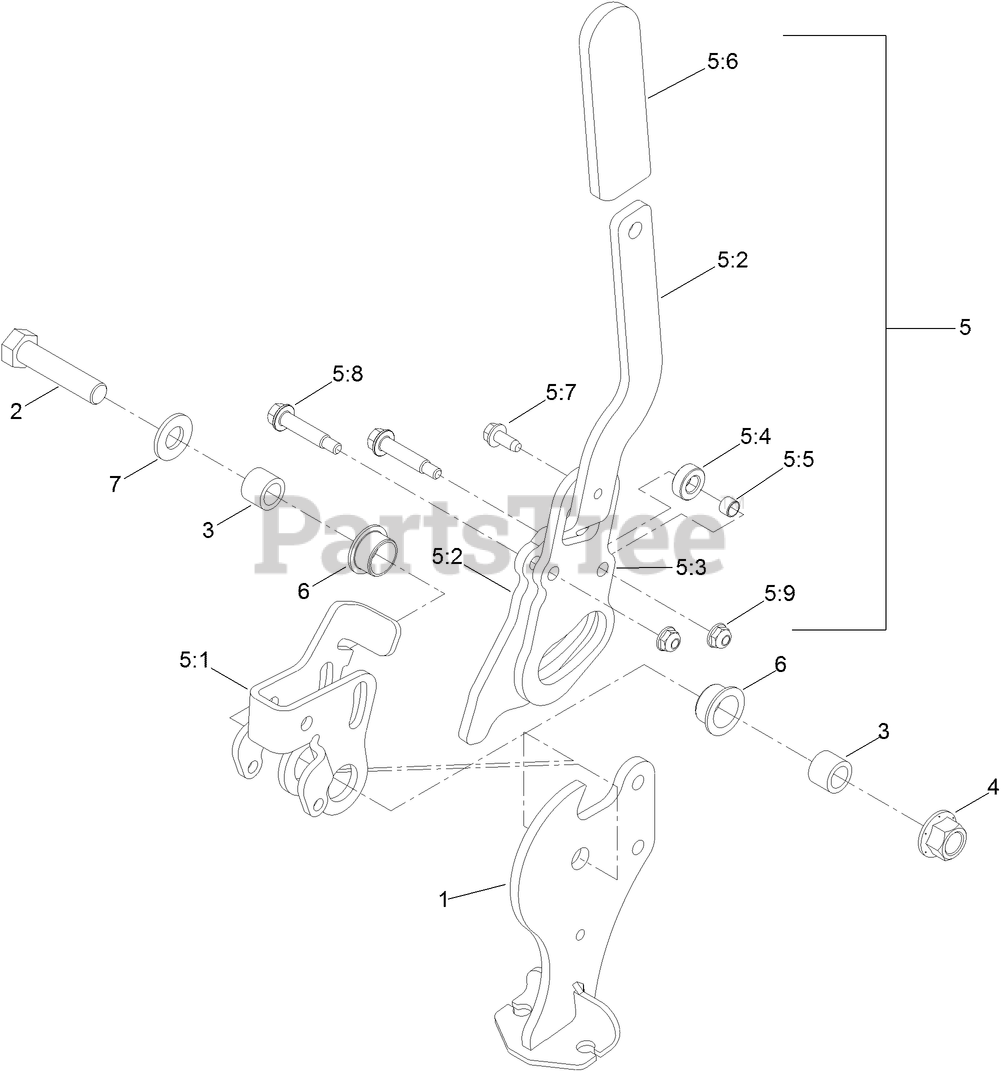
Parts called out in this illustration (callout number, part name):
1	PIVOT-BRAKE
2	SCREW-HH
3	SPACER
4	NUT-LOCK
5	HANDLE ASM
5:1	BELLCRANK-BRAKE
5:2	HANDLE-BRAKE
5:3	PLATE-HANDLE
5:4	ROLLER-BRAKE
5:5	BEARING-SLEEVE
5:6	GRIP-LEVER
5:7	SCREW-HWH
5:8	SCREW-SHOULDER
5:9	NUT-HF
6	BUSHING-FLANGE
7	WASHER-FLAT
